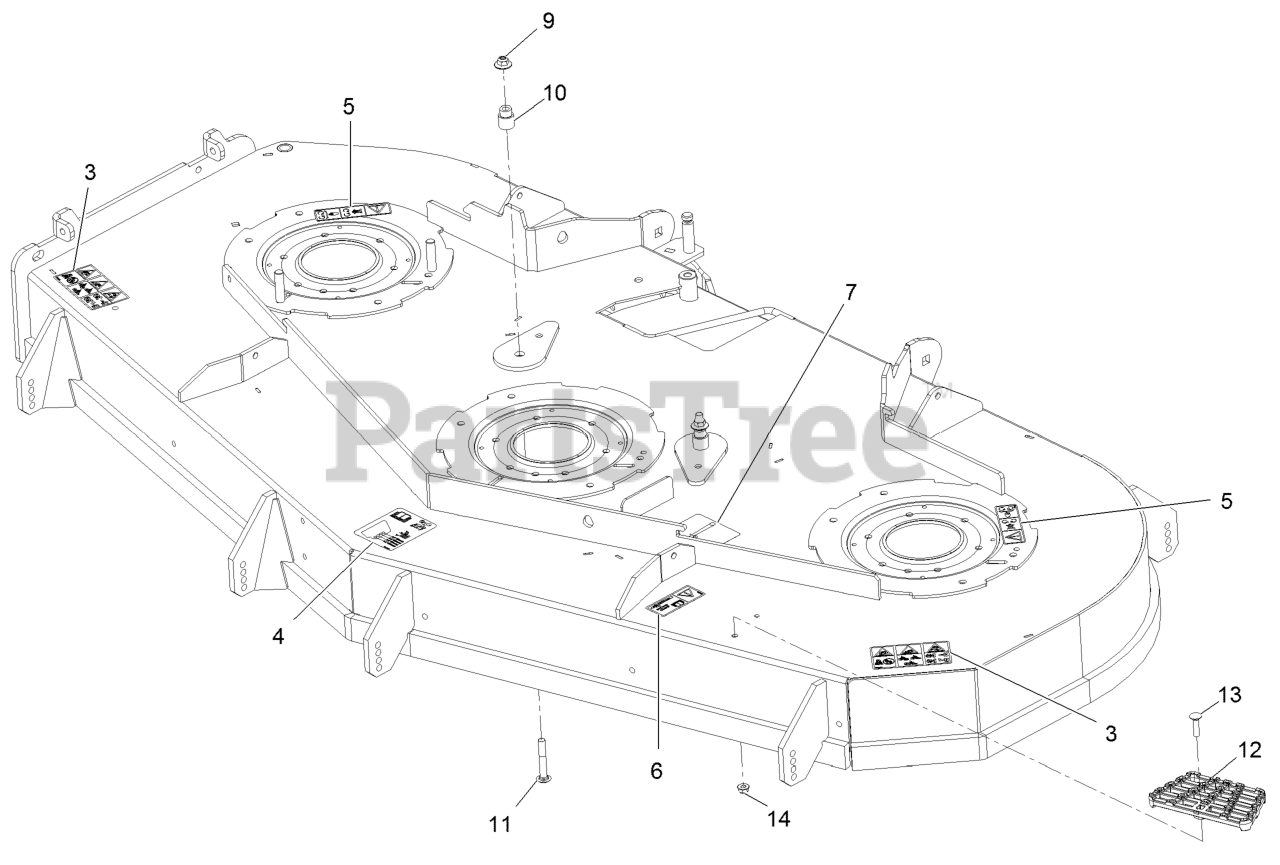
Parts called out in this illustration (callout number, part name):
3	DECAL-DANGER THROWN OBJECTS
4	DECAL-ROLLER, ANTI-SCALP
5	DECAL-COVER, MISSING
6	DECAL-BOLT TORQUE
7	DECAL-BELT ROUTING
9	Nut-Nyloc 3/8-16 Flg
10	BUSHING-IDLER
11	SCREW-CARR
12	STEP-DECK
13	Bolt-Carriage 5/16-18 X 1 1/4
14	NUT-HF, NI
